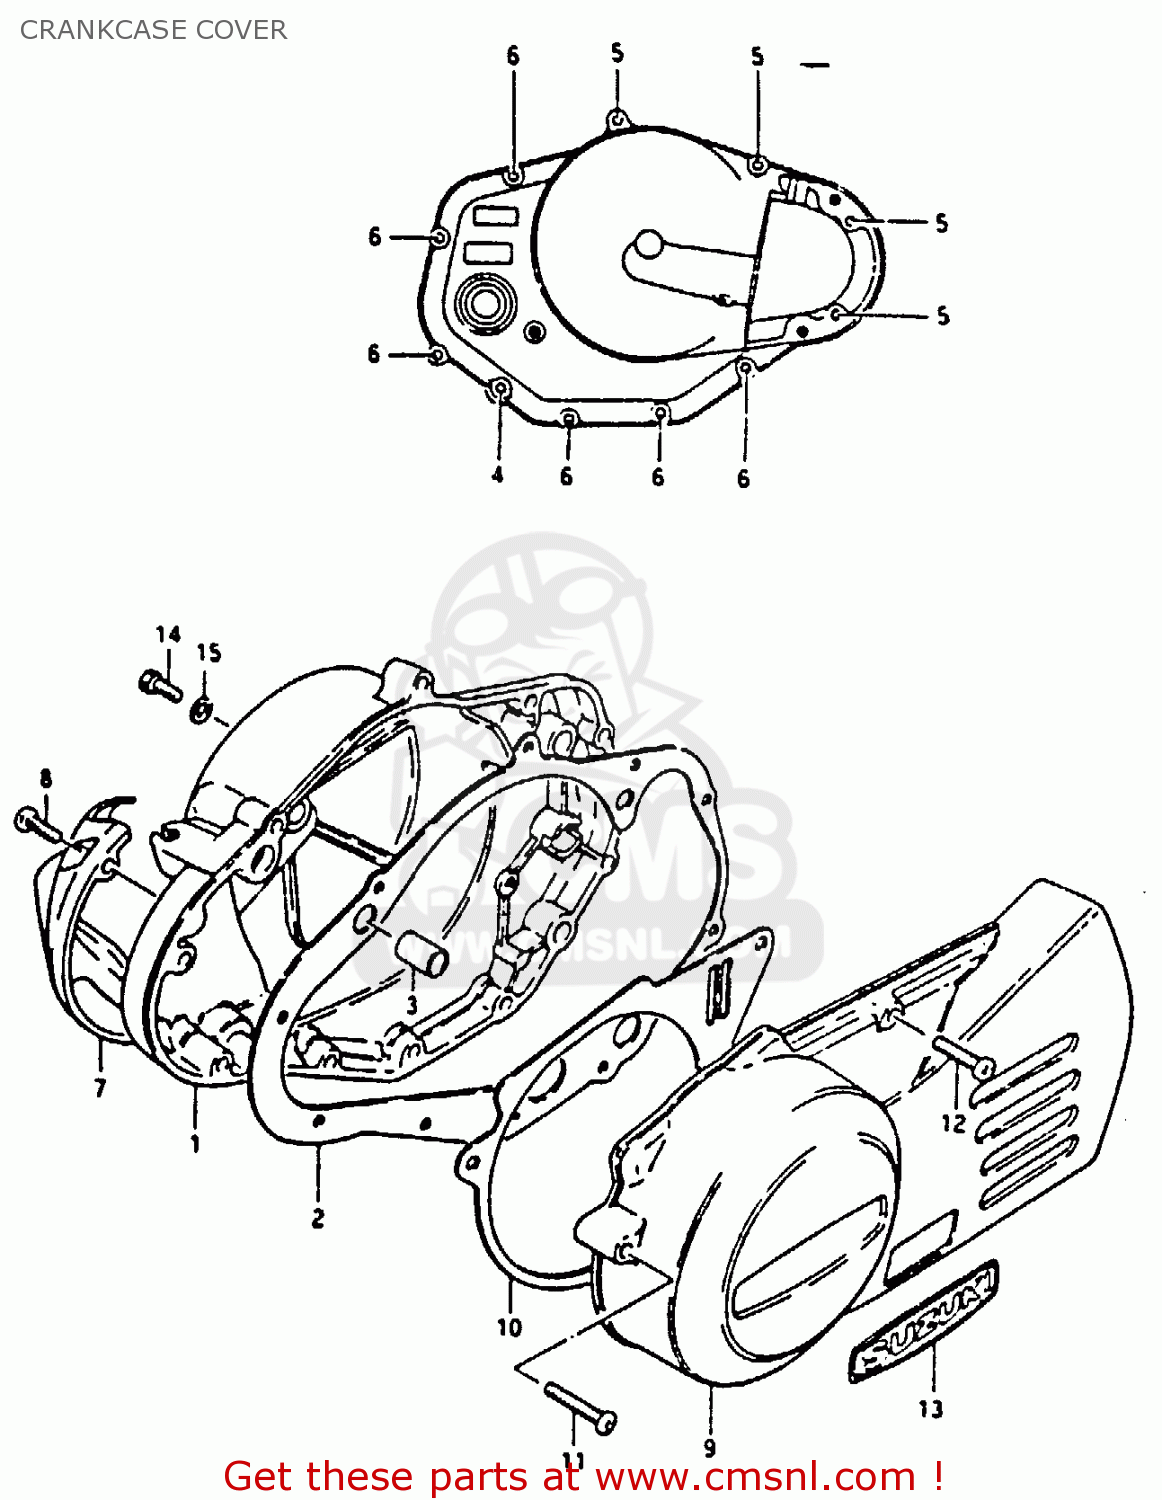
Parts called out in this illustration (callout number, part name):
1	COVER,CLUTCH
2	GASKET,CLUTCH COVER (MCA)
3	PIN
4	SCREW (6X45)
5	SCREW 6X30
6	SCREW
7	COVER,CLUTCH RELEASE ARM
8	SCREW
9	COVER,MAGNETO
10	GASKET,MAGNETO COVER (NAS)
11	SCREW 6X30
12	SCREW
13	EMBLEM,GENERATOR COVER
14	SCREW(6X10)
15	GASKET(6.2X11X1) (NAS)
